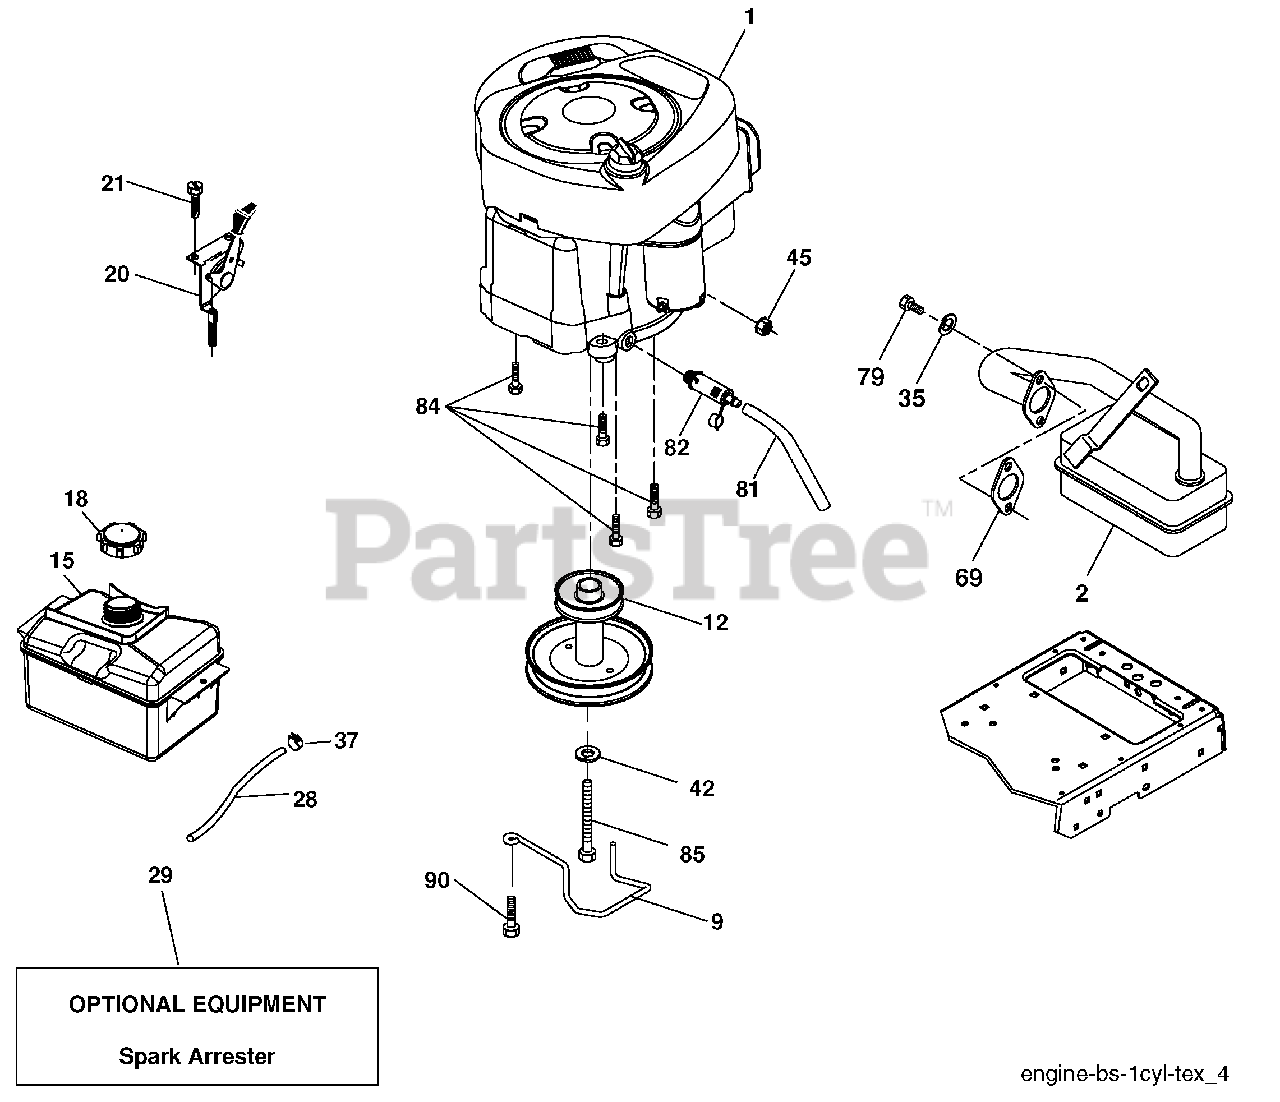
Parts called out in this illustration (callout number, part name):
2	Muffler
9	Keeper Belt Engine
12	Pulley Engine
15	Tank Fuel 2.5
18	Cap Asm
20	Control Throttle
21	Screw 10 x 3/4 Single Lead-Hex
28	Fuel Line
29	Spark Arrester Kit
35	Washer Split
37	Clamp Hose
42	Washer Lock 7/16
45	Nut Keps Hex 1/4-20 unc
69	Gasket
79	Screw Socket Head 5/16-18 x .75
81	Tube Drain Oileasy
82	Plug Drain Oil
84	Screw 3/8-16 x 1-1/4
85	Bolt Hex 7/16-20 x 4 x 5 Ga.-1.5
90	Screw 3/8-16 x 1
